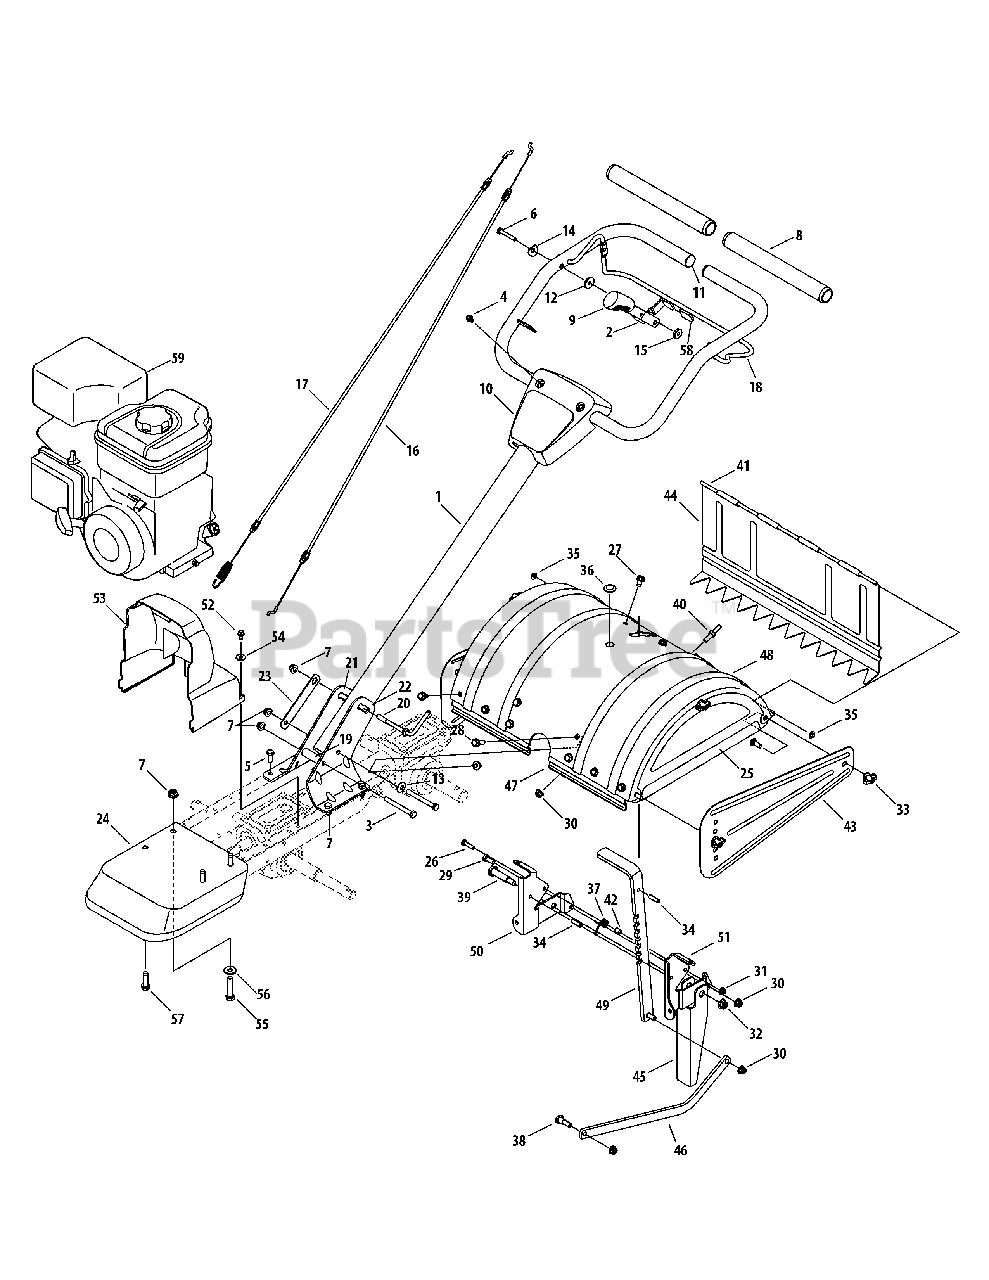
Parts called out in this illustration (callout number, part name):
1	Upper Handle Assembly
2	Reverse Handle Assembly
3	Hex Screw, 5/16-18 x 3.00
4	Hex Washer Screw, 1/4-20 x 0.500
5	Hex Washer Screw, 5/16-18 x .875
6	Hex Lock Screw, 1/4-20 x 1.62
7	Flange Lock Nut, 5/16-18
8	Foam Grip, .970 x 11.0
9	Selector Handle
10	Handle Cover
11	End Plug
12	Flat Washer, .265 x .938 x .120
13	Bell Washer, .340 x .872 x .060
14	Saddle Washer, 320 x .93 x .060
15	Shoulder Spacer, .375 x .165
16	Reverse Cable
17	Forward Cable
18	Clutch Bail
19	Spacer, .322 x .625 x 2.00
20	Handle Adjust Crank
21	RH Handle Bracket
22	LH Handle Bracket
23	Bracket
24	Front Bumper
25	End Cover Assembly
26	Hex Screw, 1/4-20 x 1.00
27	Hex Washer Screw, 5/16-18 x 0.625
28	Hex Washer Screw, 5/16-18 x .875
29	Hex Screw, 5/16-18 x .75
30	Flange Lock Nut, 5/16-18
31	Flange Lock Nut, 1/4-20
32	Flange Lock Nut, 3/8-16
33	Wing Nut w/ Bell Washer, 5/16-18
34	Spring Pin, 1/4 x 1.00
35	Cap Speed Nut, 1/4
36	Deck Hole Plug
37	Torsion Spring
38	Shoulder Screw, 5/16-18 x .405 x .435
39	Shoulder Screw, .498 x 1.635
40	Hex Screw, 5/16-18 x .75
41	Tiller Flap Rod
42	Round Spacer, .370 x .260 x .410
43	Side Shield
44	Rear Tine Shield
45	Stop Reverse Arm
46	Depth Drag Bar
47	Tine Shield Mount Bracket
48	Tine Shield
49	Depth Adjustment Bracket
50	LH Tail Bracket
51	RH Tail Bracket
52	Hex Washer Screw, 1/4-20 x .500
53	Belt Cover
54	Flat Washer, .28 x .74 x .063
55	Hex Screw, 5/16-18 x 1.50
56	Bellville Washer, .827 x .331 x .098
57	Hex Screw, 3/8-16 x 1.250
58	Reverse Handle Grip
59	Replacement Engine 12T102-0937-F8
